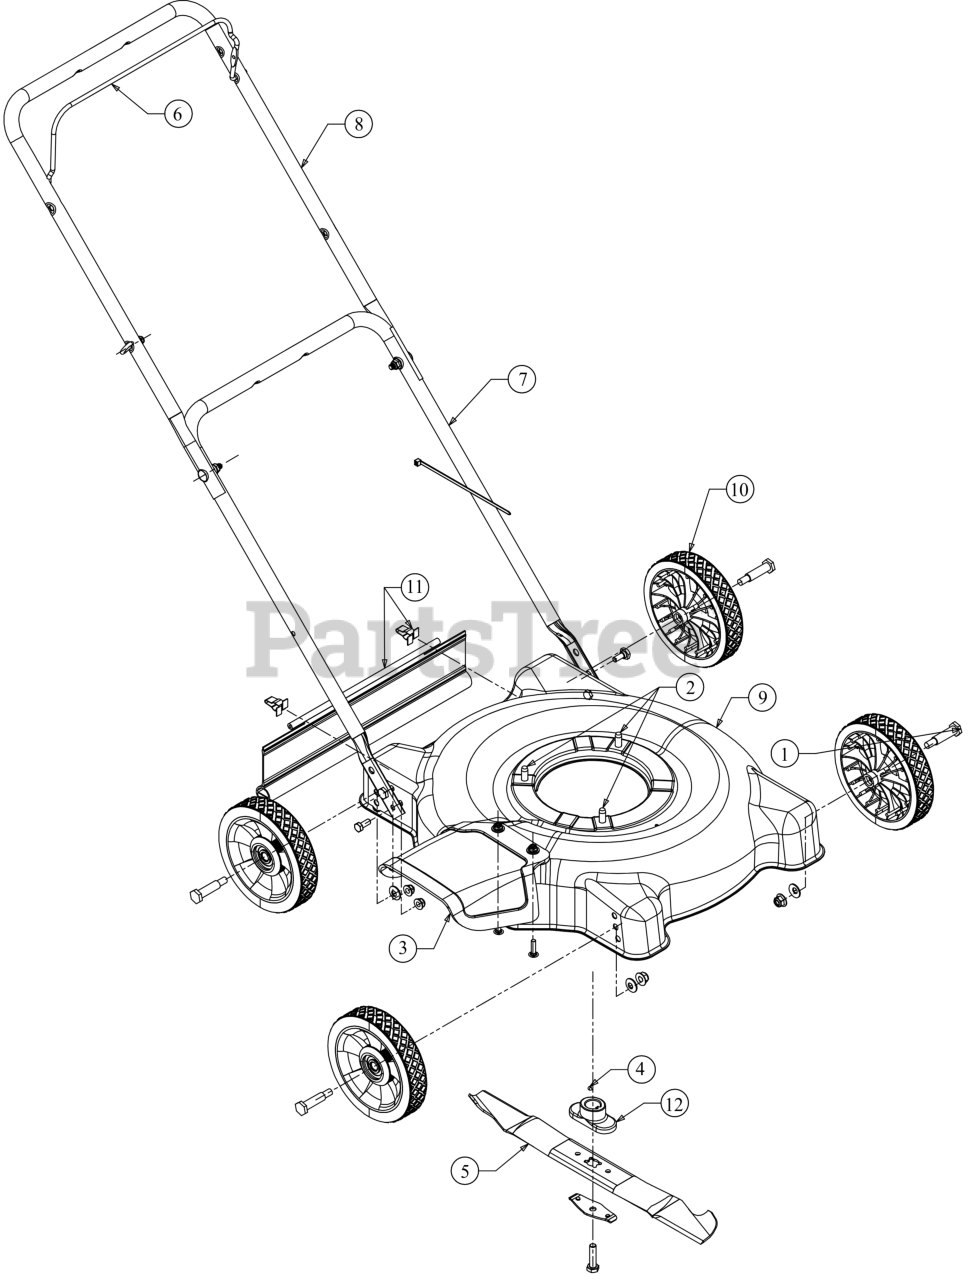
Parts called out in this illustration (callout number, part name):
1	SCREWPACK ASSEMBLY
1	CARRIAGE BOLT 5/16-18 X 1.50
1	SCREW 1/4-20 X 1 GR1
1	EYEBOLT 1/4-20
1	SCREW 5/16-18 x .75 GR5
1	FLANGE LOCK NUT 5/16-18
1	FLANGE LOCK NUT
1	CABLE TIE 7"
1	BELL WASHER .400 ID X .88 X .060
1	FLAT WASHER .28 ID X .74 OD X .063
1	SHOULDER SCREW
1	SHOULDER BOLT .498 X 1.635:3/8-16
1	SCREW 1/4-20 X 1 GR5
2	SCREW 3/8-16 X 1
3	FIXED CHUTE
4	GREASE
5	20" BLADE
5	Genuine Factory Parts 20" MULCHING BLADE (STAR)
5	20" BLADE (MULCH)
5	PWR RAKE-21" 6 IN
10	COMPLETE WHEEL
11	TRAILSHIELD-4.54 X 16.69
11	TRAILSHIELD CLIP
12	SCREW 3/8-24 X 1.50 GR8
12	BLADE BELL SUPPORT
12	BLADE ADAPTER-W/STAR
12	BLADE ADAPTER KIT
